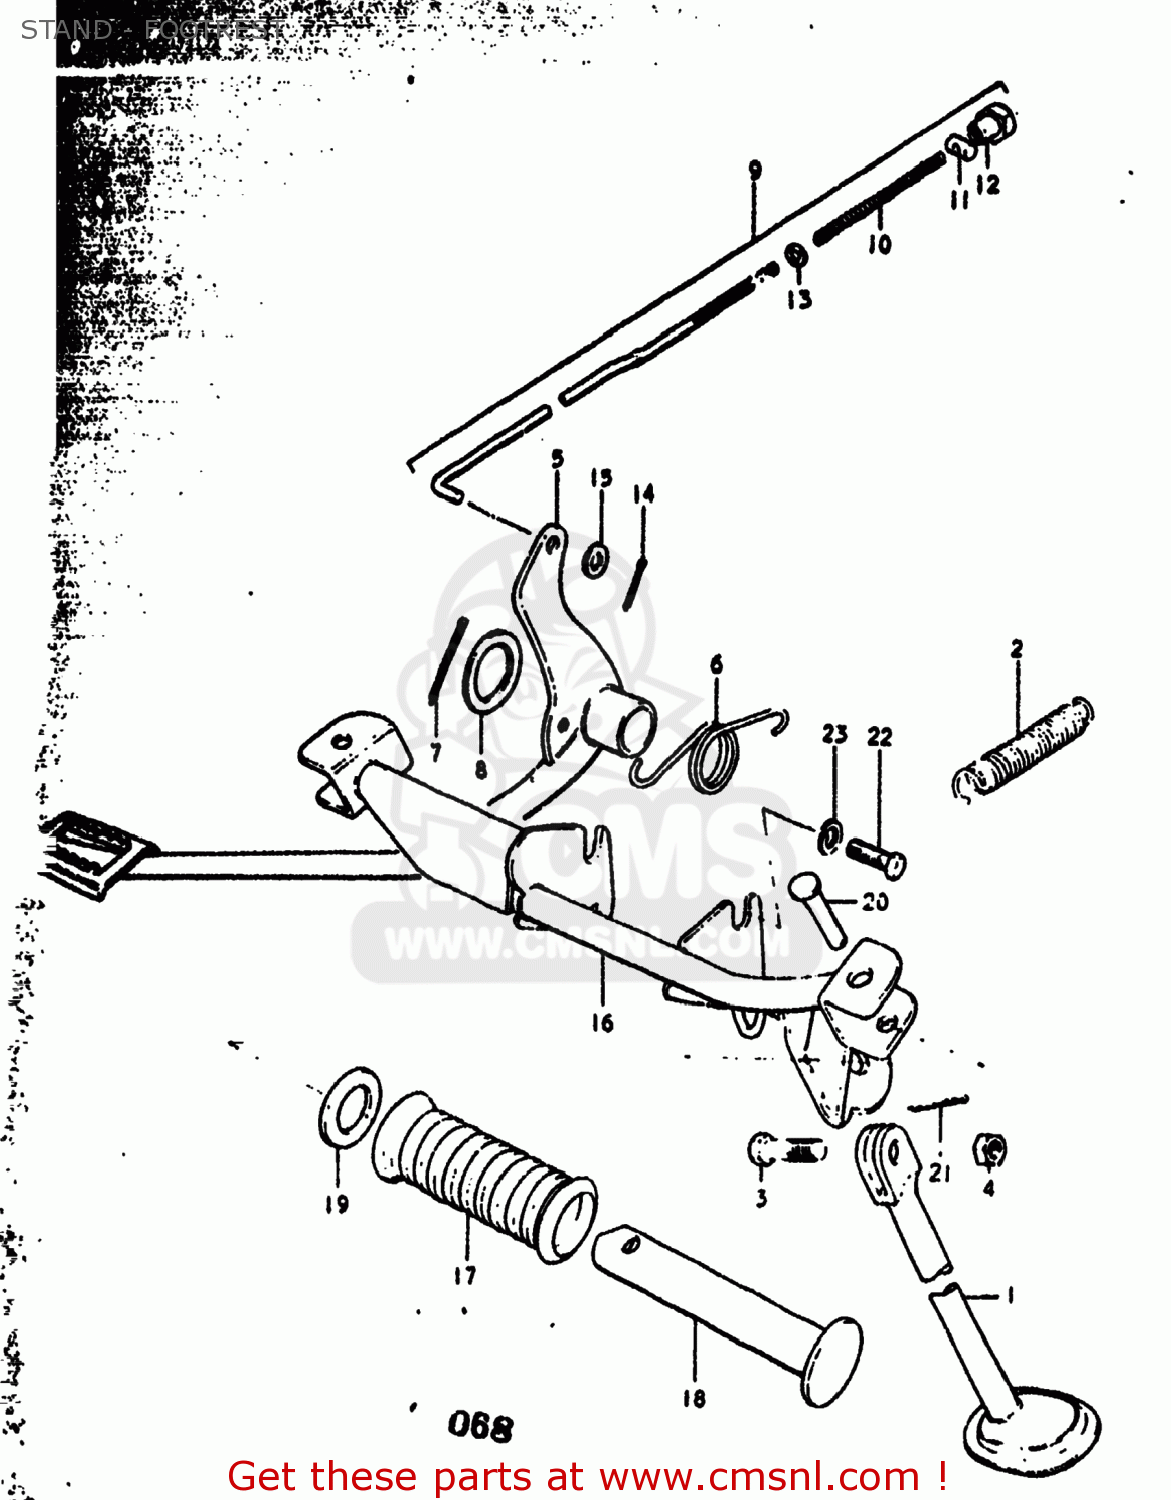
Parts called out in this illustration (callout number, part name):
1	STAND,SIDE
2	SPRING
3	BOLT
4	NUT
5	PEDAL,BRAKE
6	SPRING
7	COTTER PIN
8	WASHER(15.5X26X2.3)
9	ROD ASSEMBLY,REAR BRAKE
10	SPRING
11	PIN(11X18)
12	NUT
13	WASHER
14	PIN 20X20
15	WASHER
16	BAR,FRONT FOOTREST
17	RUBBER,PILLION FOOTREST
18	BAR,FOOTREST RUBBER
19	WASHER (19.5X32X2)
20	PIN
21	PIN 20X20
22	BOLT
23	LOCK WASHER
